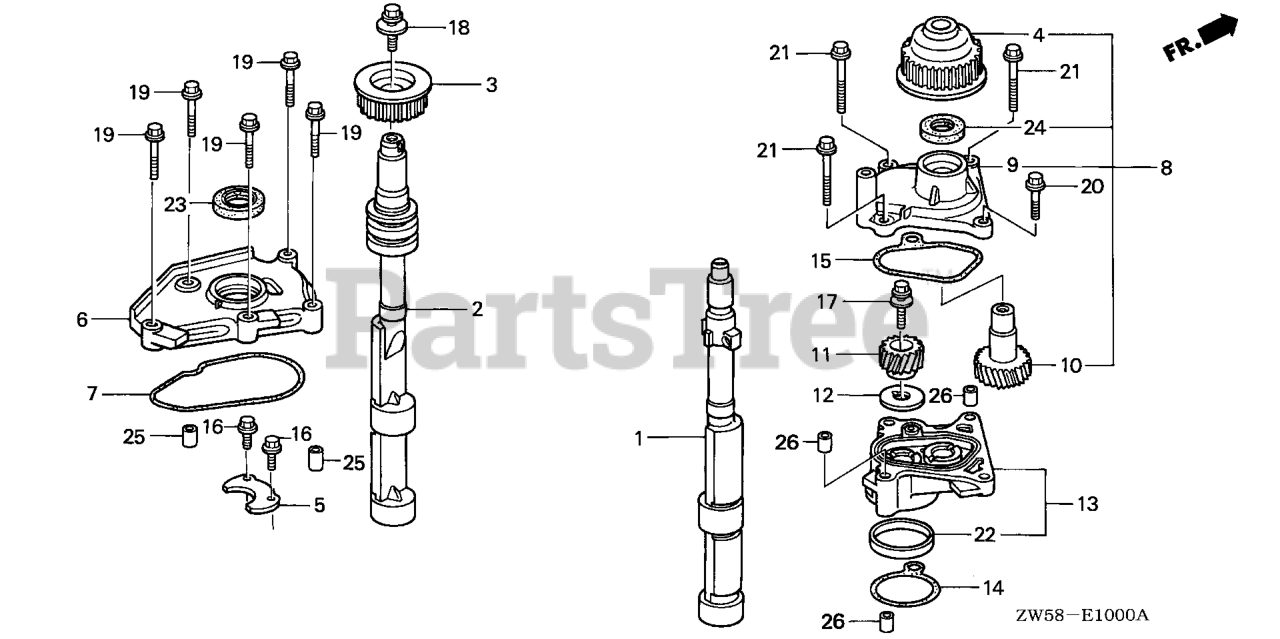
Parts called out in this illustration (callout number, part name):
1	SHAFT, RR. BALANCER
2	SHAFT, FR. BALANCER
3	PULLEY, BALANCER BELT DRIVEN (FR)
4	PULLEY, BALANCER BELT DRIVEN (RR)
5	METAL F, THRUST BALANCER SHAFT
6	COVER, BALANCER SHAFT
7	O-RING, BALANCER COVER
8	CASE, BALANCER GEAR
9	CASE, BALANCER GEAR
10	GEAR, BALANCER DRIVE
11	GEAR, BALANCER DRIVEN
12	WASHER, THRUST
13	SPACER, GEAR CASE
14	O-RING, GEAR CASE SPACER
15	GASKET B, OIL PUMP (ARAI)
16	BOLT, FLANGE (6X18)
17	BOLT-WASHER (8X33)
18	BOLT-WASHER (8X22)
19	BOLT, FLANGE (6X35)
20	BOLT, FLANGE (8X25)
21	BOLT, FLANGE (8X65)
22	PIN, DOWEL (49X10)
23	OIL SEAL (27X41X8) (NOK)
24	OIL SEAL (18X33X6)
25	PIN A, DOWEL (8X14)
26	PIN, DOWEL (10X12)
